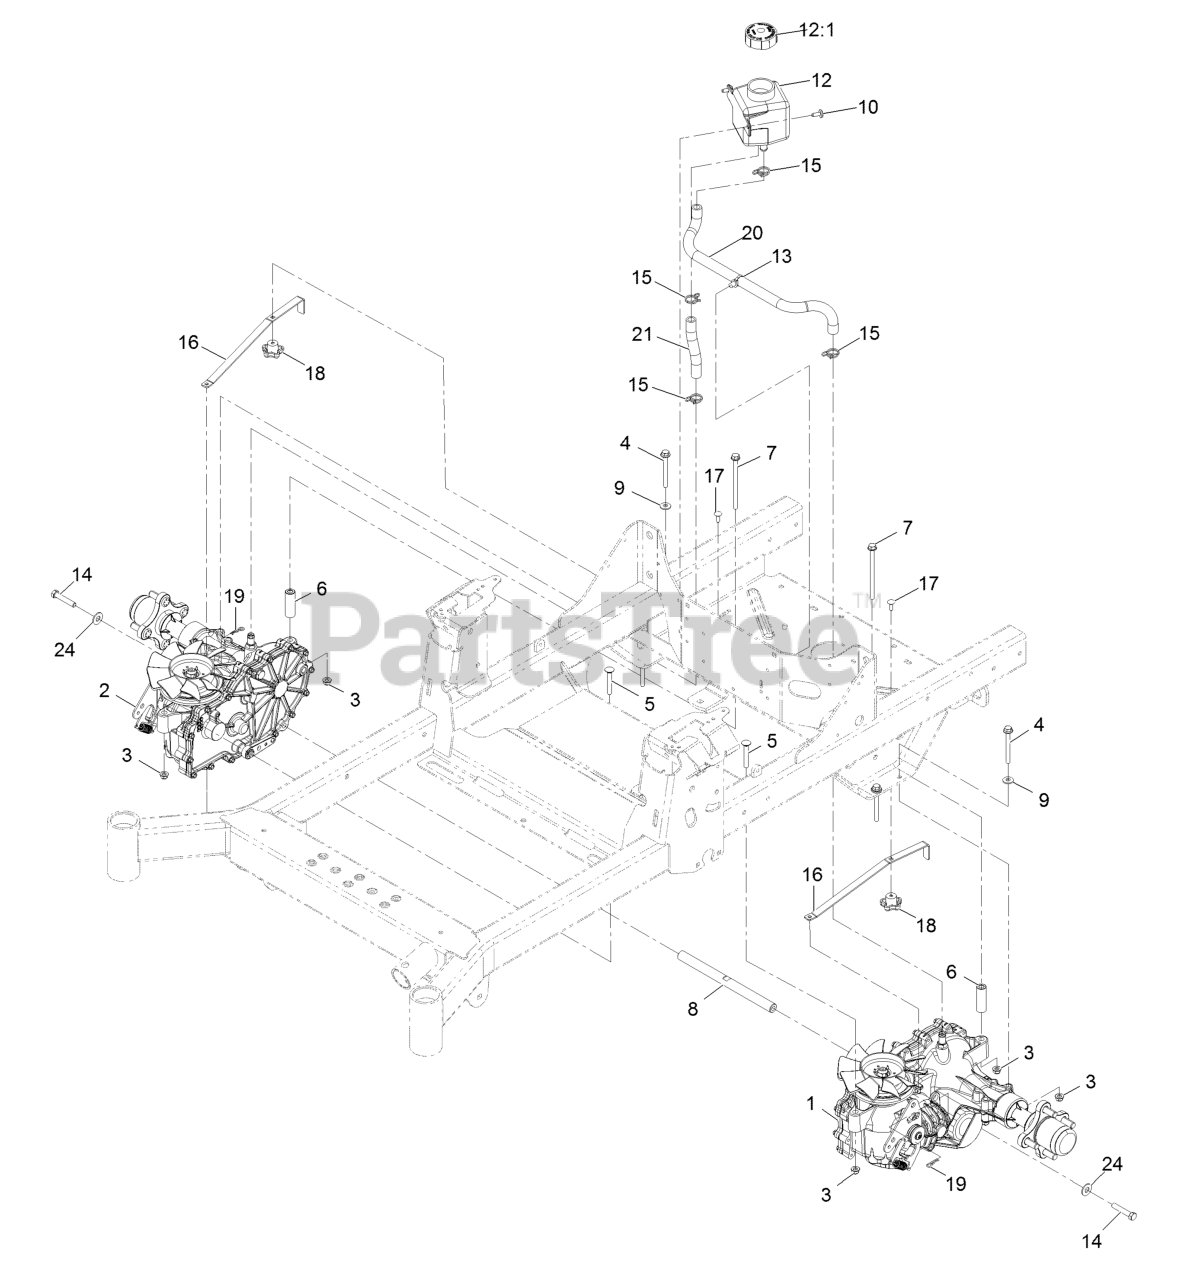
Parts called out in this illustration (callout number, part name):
1	Transaxle ASM
2	Transaxle ASM RH
3	Nut-Nyloc 5/16-18 Flg
4	Screw-HHF
5	Bolt-Carriage 5/16-18 X 2 1/4
6	Spacer-Hydro
7	Screw HHF
8	Shaft-Spacer
9	Washer-Spring Disc 5/16
10	Screw-1/4-20 X .65 Torx Plus
12	Tank-HYD
12:1	Cap-Reservoir, HYD
13	Clip-Tie
14	Screw-HH W/Loctite
15	Clamp-Hose
16	Arm-Bypass, Hydro
17	Bolt-Carriage 1/4-20 X 3/4
18	Knob-Handle
19	Hairpin-Cotter
20	Hose-Hydraulic
21	Hose-Hydraulic
24	Washer-3/8 Std
